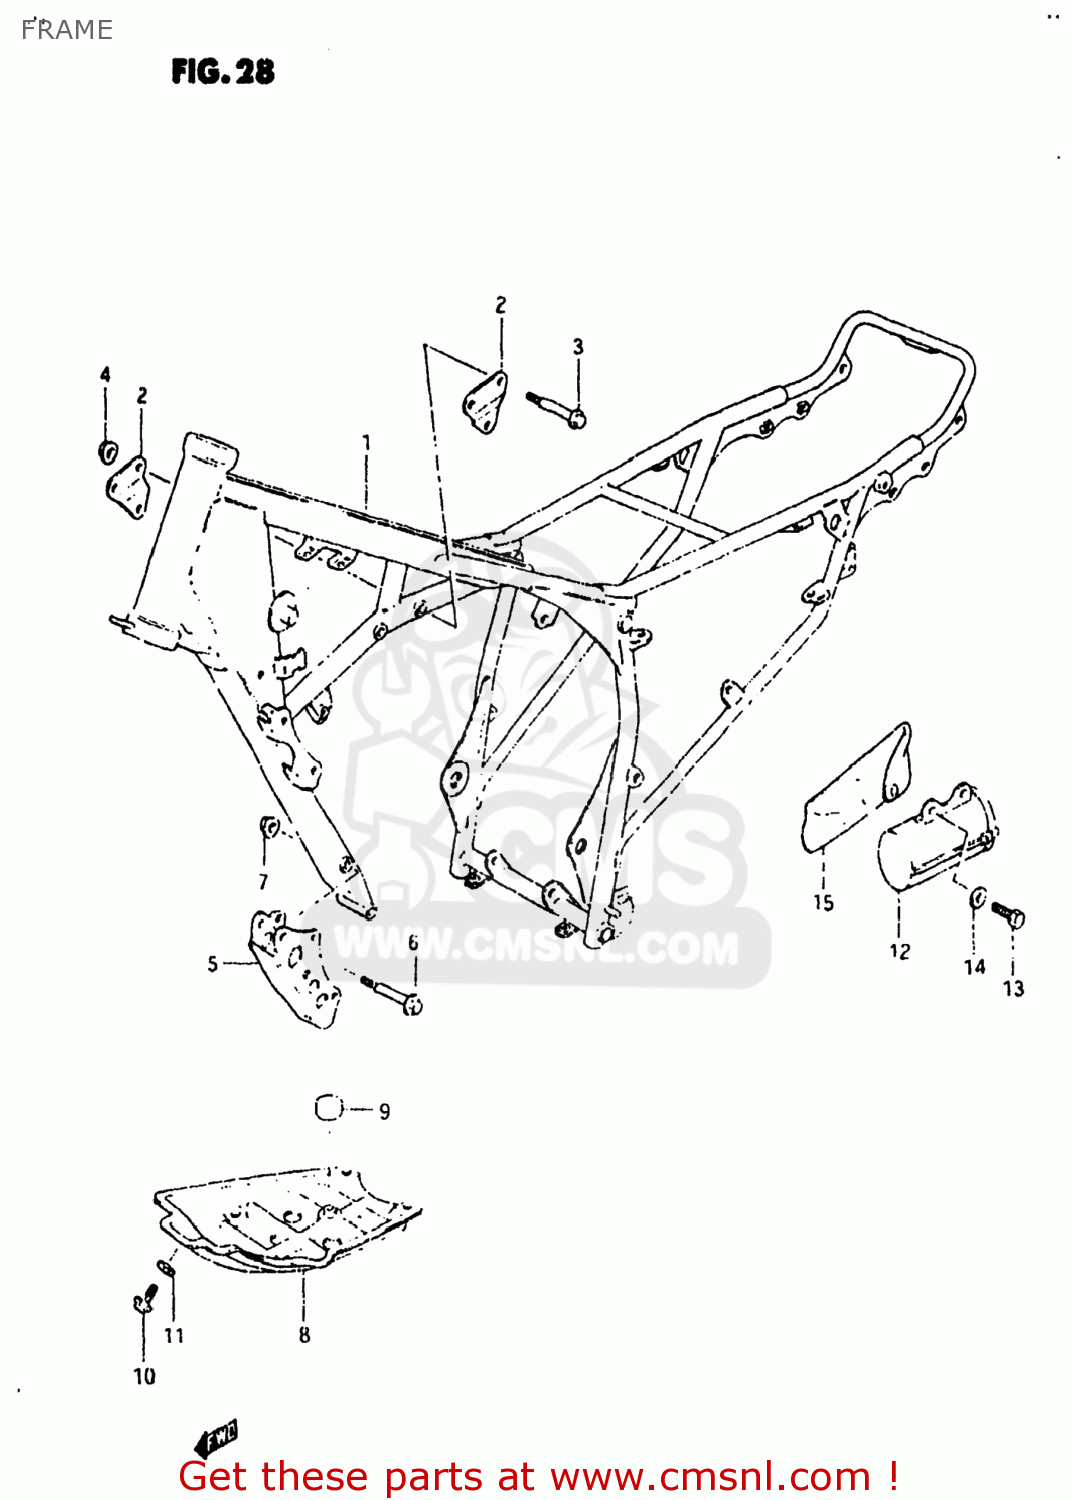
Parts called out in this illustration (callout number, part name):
1	FRAME
2	PLATE,ENGINE MOUNTING
3	BOLT
4	NUT
5	PLATE,ENGINE MOUNTING
6	BOLT
7	NUT
8	PROTECTOR,ENGINE
9	CUSHION
10	BOLT
11	WASHER
12	HOLDER,TOOL
13	BOLT, UPPER
14	WASHER (6.5X18X1.6)
15	TOOL SET
